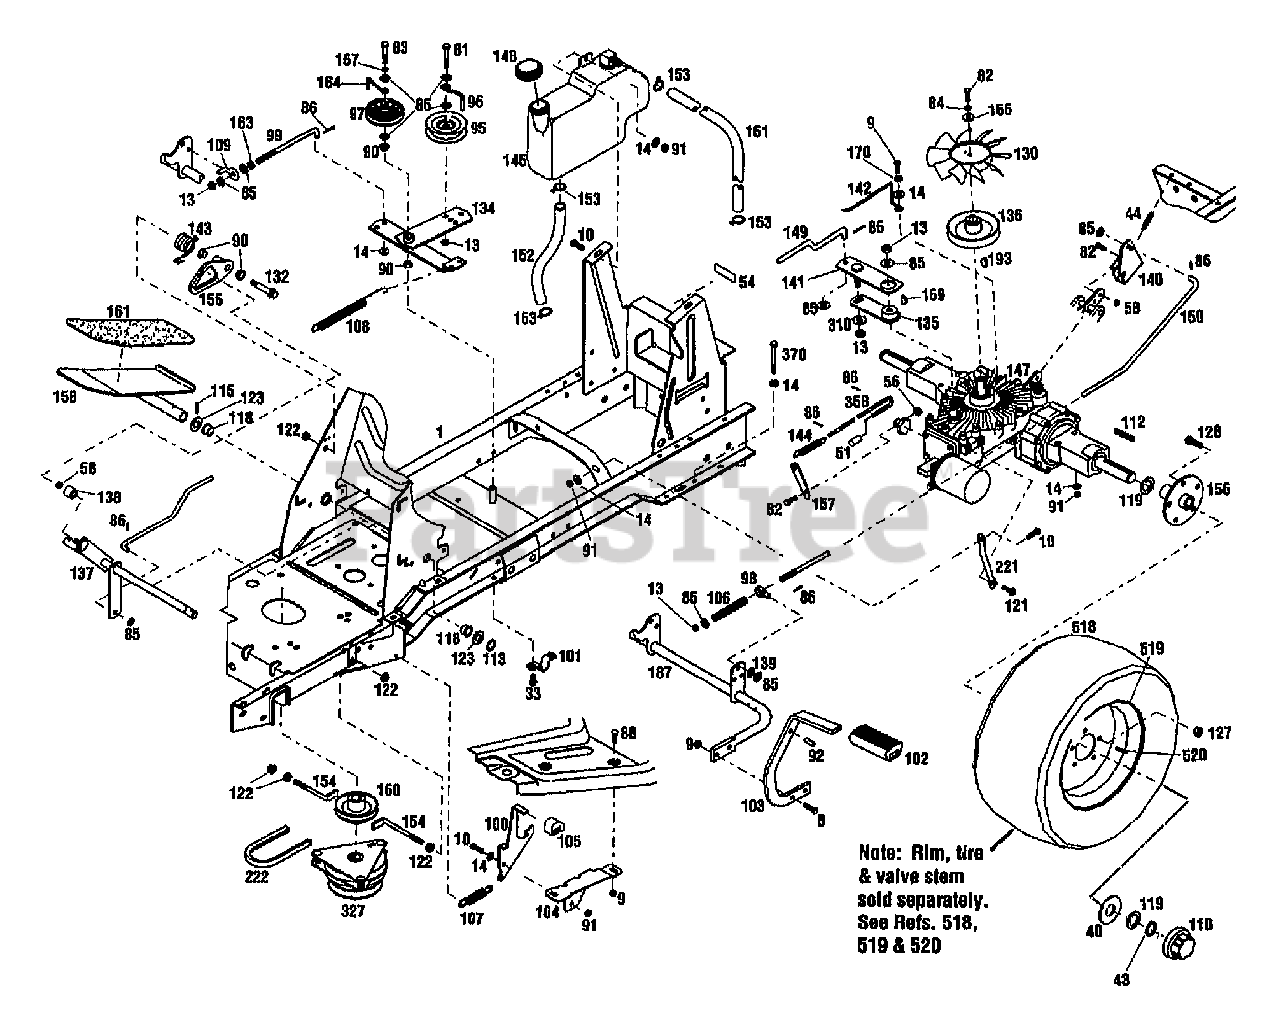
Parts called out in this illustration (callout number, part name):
8	SCR-HH 5/16-18X1.0 G5 ZP
9	NUT-HFLK 5/16-18 ZP
10	SCR-HHC 5/16-18X.75 GR 5 ZP
13	NUT-LOCK 3/8-16
14	WASHER-FLAT 5/16 SAE
33	SCR-HFLK 5/16-18X.75
40	WASHER-SPECIAL .75X2.5
43	RING-HEAVY EXT HD 1.0 ID
44	SPRING-EXTENSION
51	GRIP-HANDLE
54	DECAL-TRANS RELEASE
56	NUT-HF/LK 1/4-20 ZP
58	NUT-HT LK 1/4-20
81	SCR-HH 3/8-16X2.0 G5 ZP
82	SCR-HH 1/4-20X1.0
84	WASHER-LK .25 ZP
85	WASHER-FLAT 3/8 SAE
86	PIN-COTTER .09X.75 ZP
88	SCR-CARR 5/16-18X.62 G2 ZP
90	BUSHING-.5X.5 NYLON FLNG
91	NUT-TOP/LK 5/16-18 ZP
92	PIN-.312X.75
96	GUIDE-BELT
98	SWIVEL
99	ROD-CLUTCH
100	LATCH-BRAKE CLUTCH USE1771514
101	CLIP-CLAMP .75 ID
102	PAD-FOOT PEDAL
103	PEDAL-BRAKE
104	BRKT-BRAKE LOCK
105	PAD-BRAKE
106	SPRING-COMPRESSION
107	SPRING-EXTENSION
109	ROD-PIVOT
110	CAP-HUB
112	KEY-.25 SQ X 2.0
113	RING-RETAIN .625 ID
115	PIN-ROLL .188X1.0
118	BEARING-FLANGE
119	WASHER-SPEC
121	SCR-HFLK 5/16-18X.50 ZP
122	NUT-HFLK 3/8-16 ZP
123	WASHER-1.115X.637X.06
127	NUT-LUG 7/16-20
128	BOLT-WHEEL
130	FAN-HYDRO TRANSMISSION
132	SCR-SHLDR 3/8-16
134	ARM-IDLER
135	ARM-HYDRO
136	PULLEY-HYDRO
137	SHAFT-HYDRO PIVOT
138	BEARING-BALL
139	WASHER-.376 DIA
140	BRKT-BRAKE HYDRO
141	ARM-CONTROL HYDRO
142	GUIDE-BELT
143	SPRING-TORSION
144	SPRING
145	RESERVOIR-OIL
147	TRANSAXLE-HYDROSTATIC
148	CAP-TANK
149	ROD-CONTROL HYDRO
150	ROD-BRAKE
152	HOSE-HYDRAULIC 5/8
153	CLAMP-HOSE 5/8
154	RETAINER-CLUTCH
155	ARM-RETURN NEUTRAL HYDRO
156	HUB-WHEEL
157	VALVE-DUMP
158	ASSM-PEDAL HYDRO
160	PULLEY-ENGINE
161	PAD-FOOT PEDAL
163	NUT-HEX 3/8-16 ZP
164	GUIDE-BELT
166	WASHER-FLAT 1.25X.28X.062 ZP
169	KEY-WOODRUFF .125X.5
170	WASHER-LK .312 ZP
187	ASSM-BRAKE PEDAL
193	KEY-WOODRUFF
221	SUPPORT-TRANSMISSION
310	WASHER-LK .375 PYRAMIDAL
327	CLUTCH-ELECTRIC
370	SCR-HH 5/16-18X3.0
519	RIM-WHEEL REAR
520	STEM-VALVE
